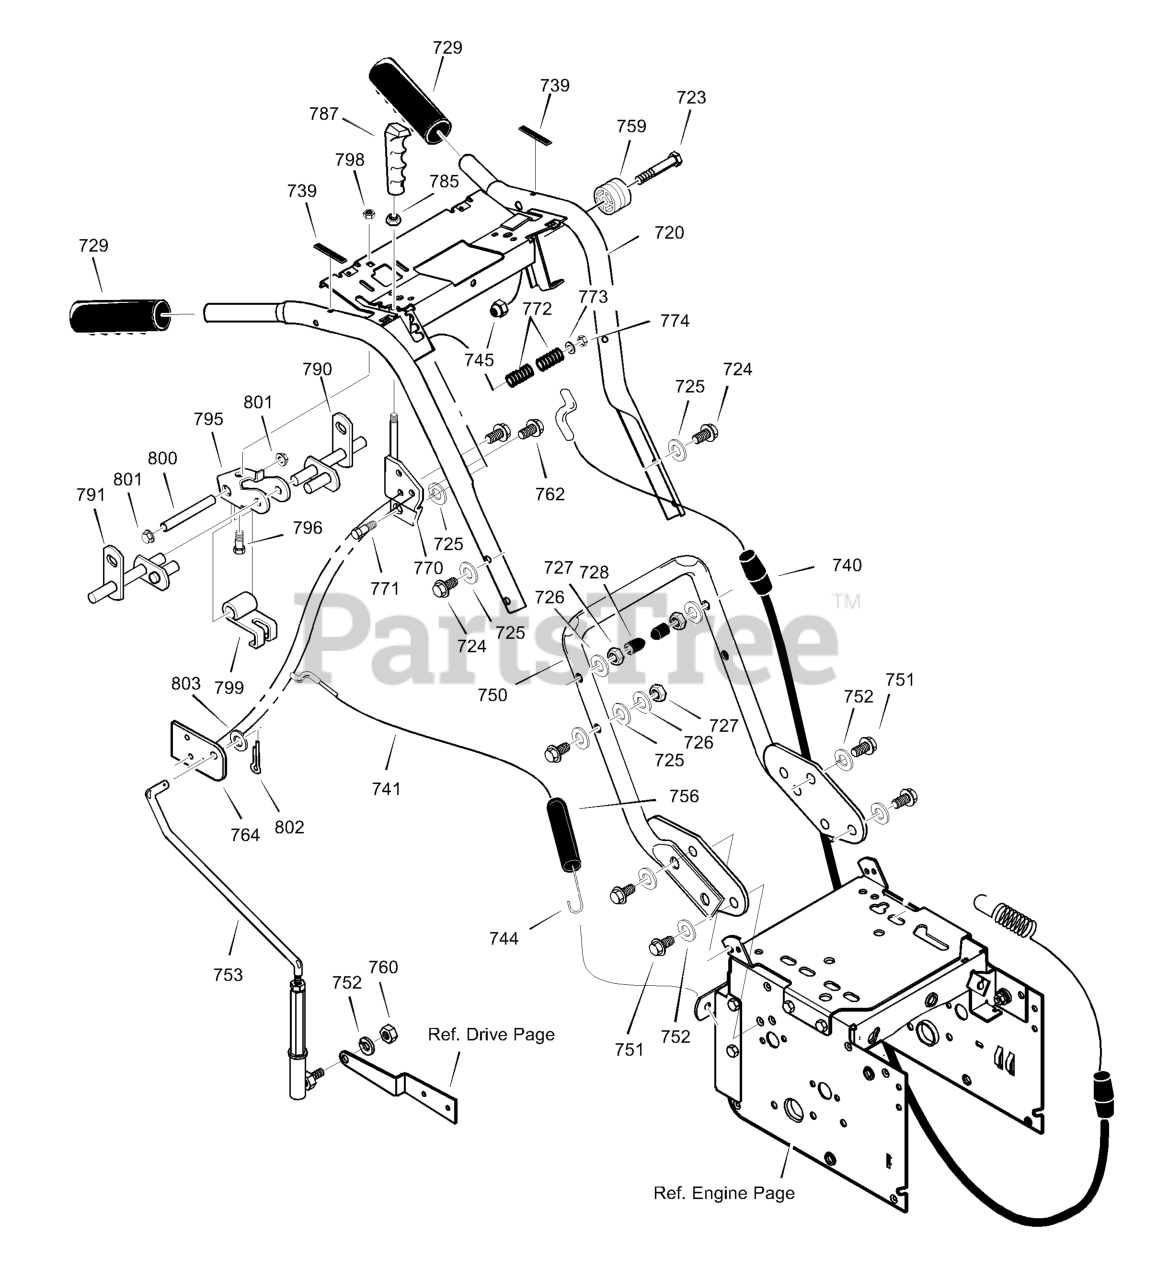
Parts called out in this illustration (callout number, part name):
720	ASSY., HANDLE
724	SCREW
725	WASHER, FLAT
726	WASHER
728	STOP, PLASTIC
729	GRIP, HANDLE
739	BUMPER
740	CABLE, CLUTCH
741	CABLE, CLUTCH
744	SPRING, CLUTCH
745	NUT, HEX
750	HANDLE, LOWER
751	SCREW
752	WASHER, SPTLK
753	ASSEMBLY, ROD & BALL JOINT
756	BOOT, CABLE
759	SPOOL, CABLE
760	NUT, 5/16-24
762	SCREW, 1/4-20 X 0.63
764	BRACKET, SPEED CONTROL
770	BRACKET, SHIFT
771	SCREW
773	WASHER, FLAT
774	NUT, HEX
785	NUT, HEX
787	KNOB, SHIFT
790	ROD, ASSY LH
791	ROD, ASSY RH
795	BRACKET, CAM
796	SCREW
798	NUT, NYLOCK
799	CAM LOCK
800	PIN, SPRING PIVOT
801	NUT, PUSH ON
802	PIN, COTTER
803	FLATWASHER
